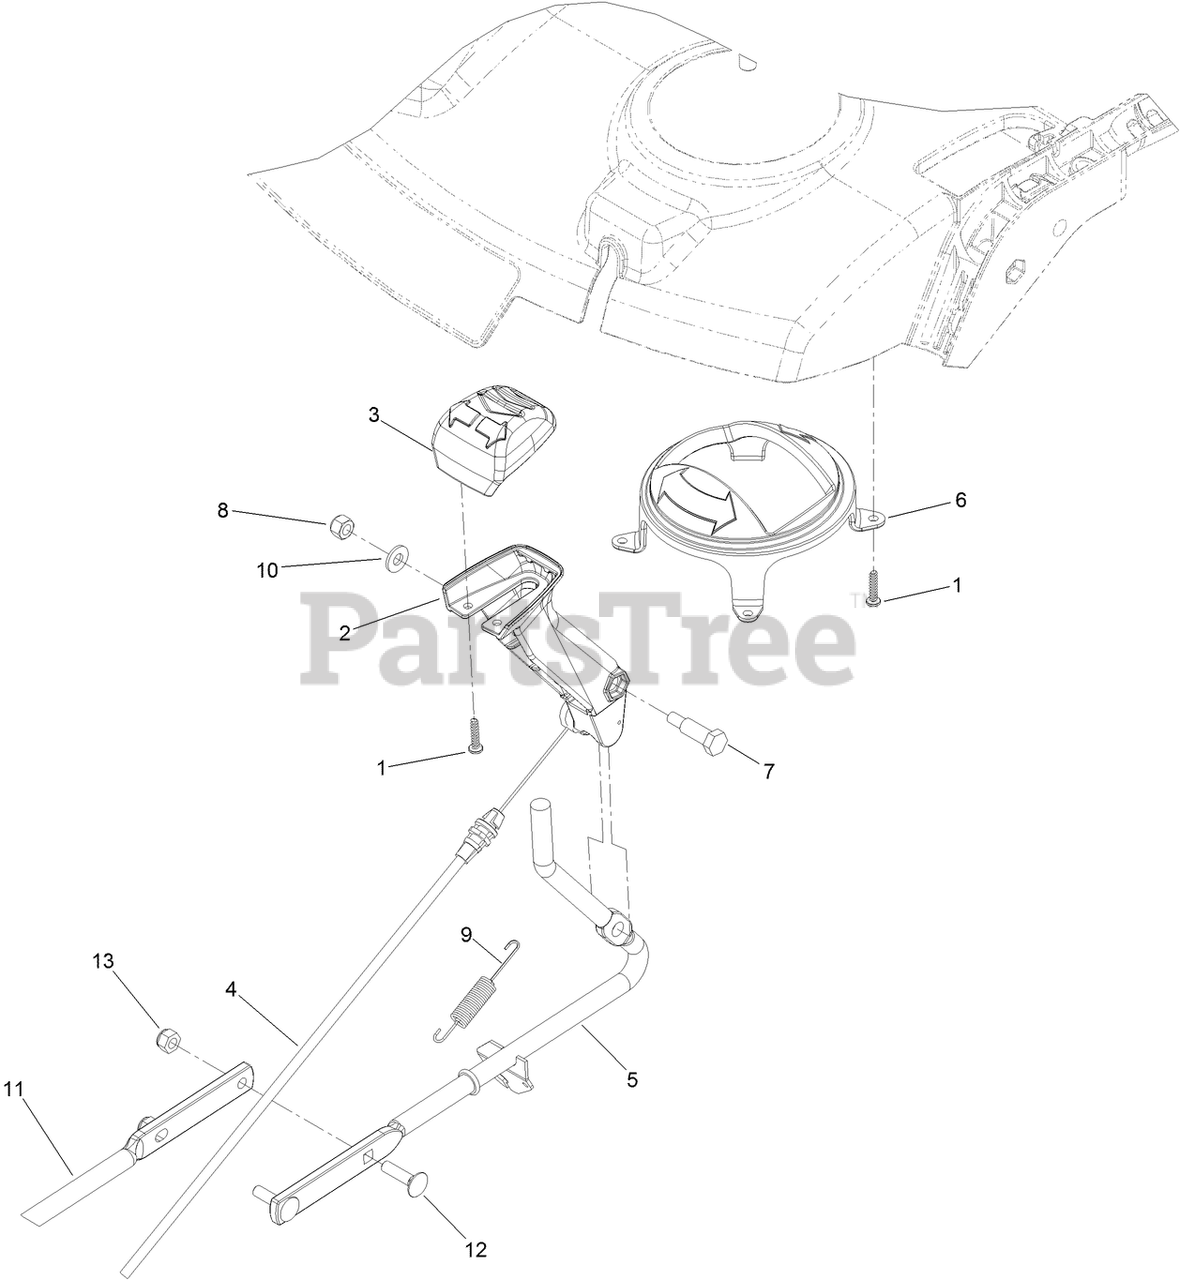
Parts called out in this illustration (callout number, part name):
1	SCREW-PPH
2	LEVER-CONTROL, CHUTE
3	CAP-CHUTE CONTROL LEVER
4	CABLE-RELEASE, CHUTE
5	CHUTE ROD ASM
6	INSERT-LEVER, QUICK
7	SCREW-SHOULDER
8	NUT-LOCK, NI
9	SPRING-RETURN, LEVER
10	WASHER-FLAT
11	ROD-CHUTE, FRONT
12	BOLT-CARR
